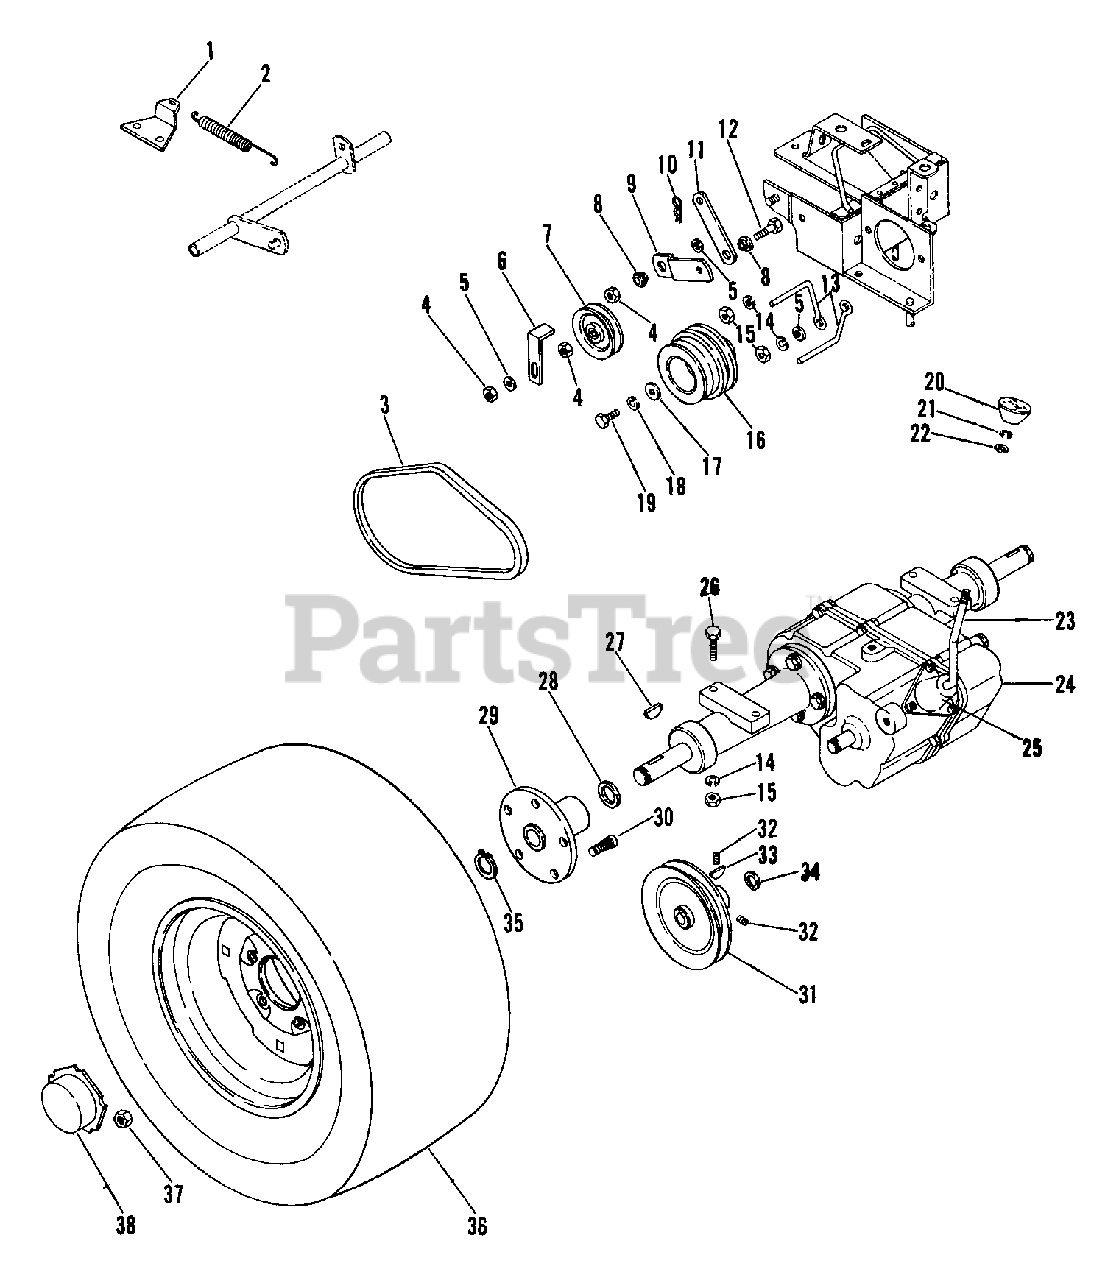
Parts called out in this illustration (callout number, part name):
1	SPRING MOUNT
2	SG-TENS .091X.56X6.12 WLD 40
3	V-BELT, 5L-WRAPPED
4	NUT-LK-JAM-CTR .375-16 PL
5	WSHR-FL-STL.406X.812X.065PL
6	BELT FINGER
7	IDLER-V 3.06 X .38
8	SHOULDER SPACER
9	IDLER ARM
10	PIN-HAIR INT .08X.38X1.42 YWZC
11	IDLER LINK
12	BLT-HEX .38-16X2.00 PL GR2
13	BELT FINGER
14	WSHR-LK .375X.115 HVY PL
15	NUT-HEX .375-16
17	WSHR-FL-STL .328X1.0X.094
18	WSHR-LK .312X.097 PL HVY
19	BLT-HEX .31-18X.75 PL GR5
20	SHIFT BALL
21	WSHR-LK-INT .375X.035 PL
22	WSHR-FL-STL .380X.626X.033
23	SHIFT LEVER
24	TRANSAXLE ASSEMBLY
25	SCR-CAP FLGHH .25-20X.75 GR 8
26	BLT-HEX .38-16X1.50 PL GR5
27	KEY-WDRF .25X1.125X.484ANSI809
28	WSHR-FL-STL 1.010X1.505X.062PL
29	WHEEL HUB
30	BLT-LUG SERNKHDND .44-20X1.188
31	PLY-V 6.00 X .75 W/KEY CLARK
32	SCR-SET .32-18X.38 SKHCUPNL OH
33	KEY-WDRF .188X.75X.313 SAE 9
34	WSHR-FL-STL .754X1.000X.032
35	RG-RTNG-EXT 1.00X.042
36	T/WHL ASSY 10.50X23
36	T/WHL ASSY
36	WHL 12X8.50
36	TIRE 23X10.5-12
37	NUT-LUG .437-20 YWZC
38	REAR HUB CAP
